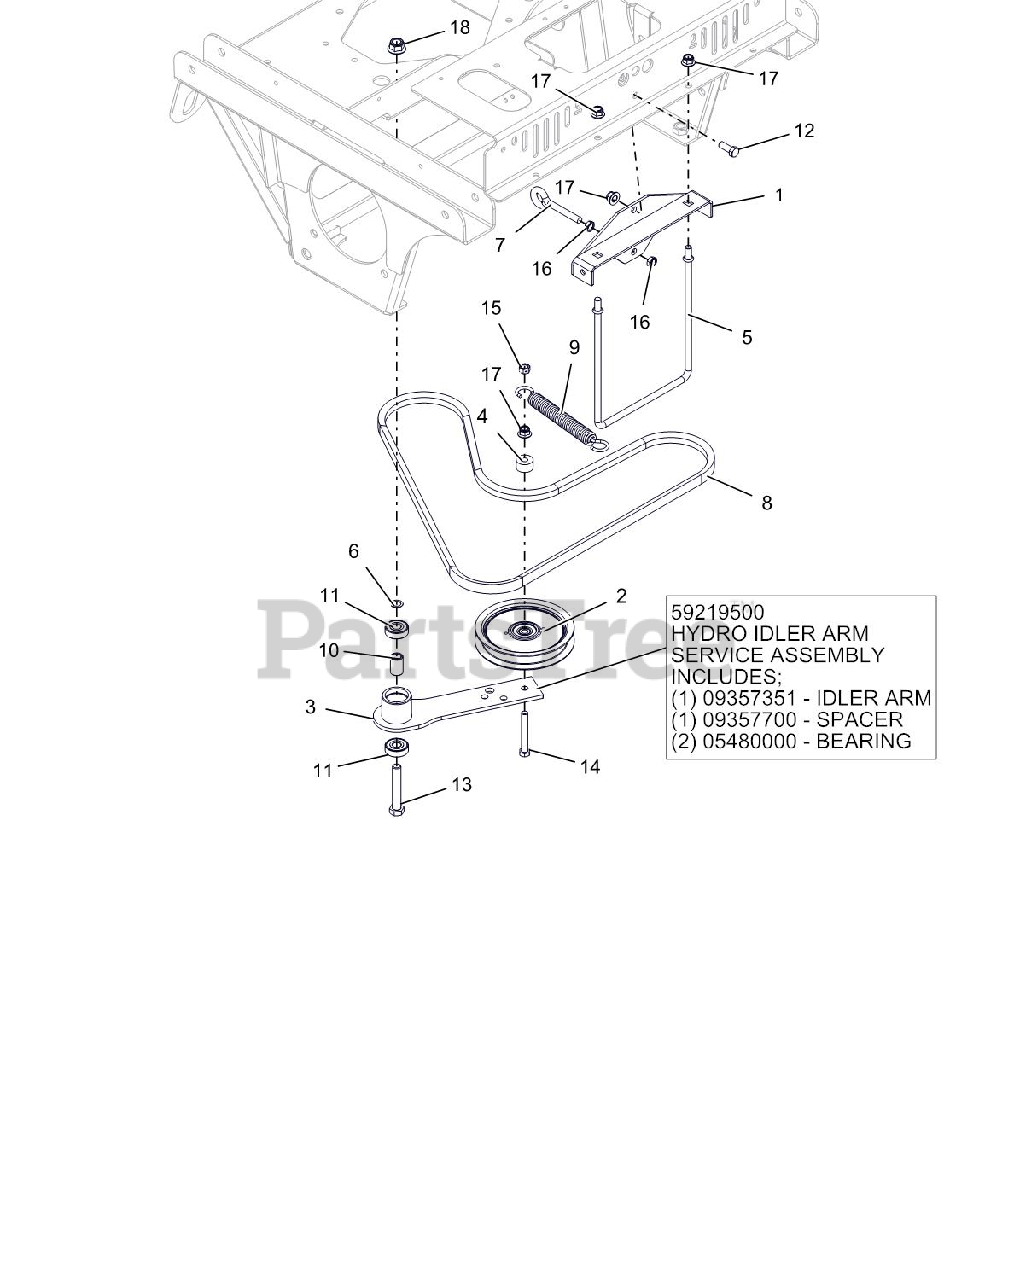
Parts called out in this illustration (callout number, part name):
1	SPRING ANCHOR BRKT WMT - BLACK
2	IDLER, FLAT-5.00X.75
3	BRG-BALL .50X1.38X.438 SEALED
3	SPACER .510 X .75 X 1.1485
3	KIT, HYDRO IDLER ARM PT200/400
3	HYDRO DRIVE IDLER ARM WMT- BLK
4	SPACER .390X1.000X.562
5	ROD, BRAKE MTG
6	WASHER, .500X.750X.020 THRUST
7	BLT-EYE .375-16X2.50 YWZC
8	V-BELT, COGGED B-RAW EDGE
9	SPRING, EXTENSION
10	SPACER .510 X .75 X 1.1485
11	BRG-BALL .500X1.38X.437
12	@BLT-HEX .38-16X1.00 GR5 YWZC
13	@BLT-HEX .50-13X3.00 GR5 YWZC
14	@BLT-HEX .38-16X2.75 GR5 YWZC
15	@NUT-LK-CTR .38-16 YWZC
16	NUT-HEX-JAM .375-16 YWZC
17	@NUT-LK-NYL-FLG .38-16 YWZC
18	@NUT-LK-NYL-FLG .50-13 YWZC
